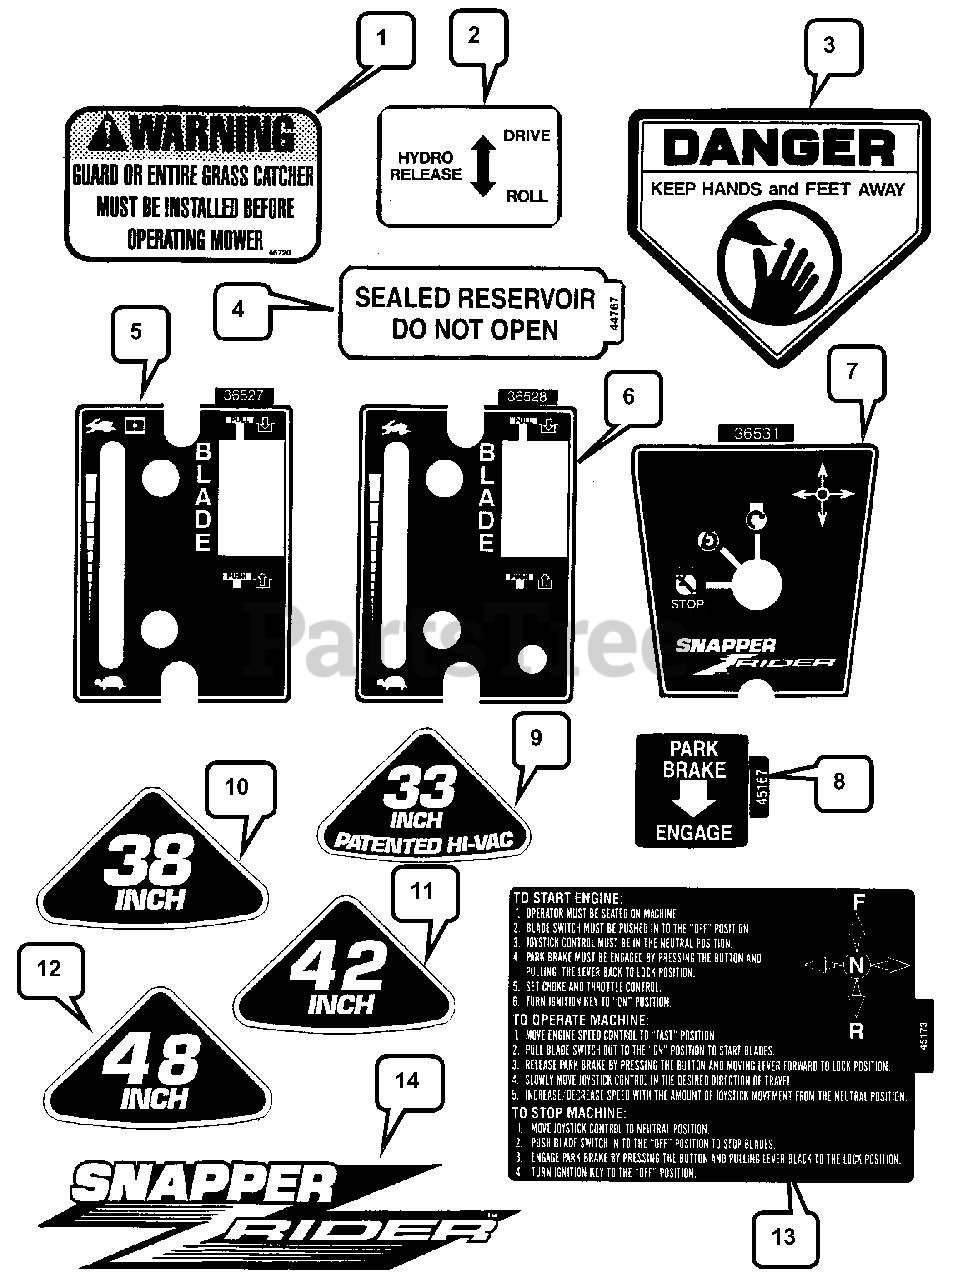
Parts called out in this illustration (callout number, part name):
1	DECAL, Warning Chute Deflector
2	DECAL, Hydro Release
3	DECAL, CPSC
4	DECAL, Hydro Reservoir
5	DECAL, Throttle Control
6	DECAL, Throttle Control
7	DECAL, Ignition Switch
8	DECAL, Park Brake
9	DECAL, 33" Hi-Vac
10	DECAL, 38"
11	DECAL, 42"
12	DECAL, 48"
13	DECAL, Operation
14	DECAL, SNAPPER Z Rider
